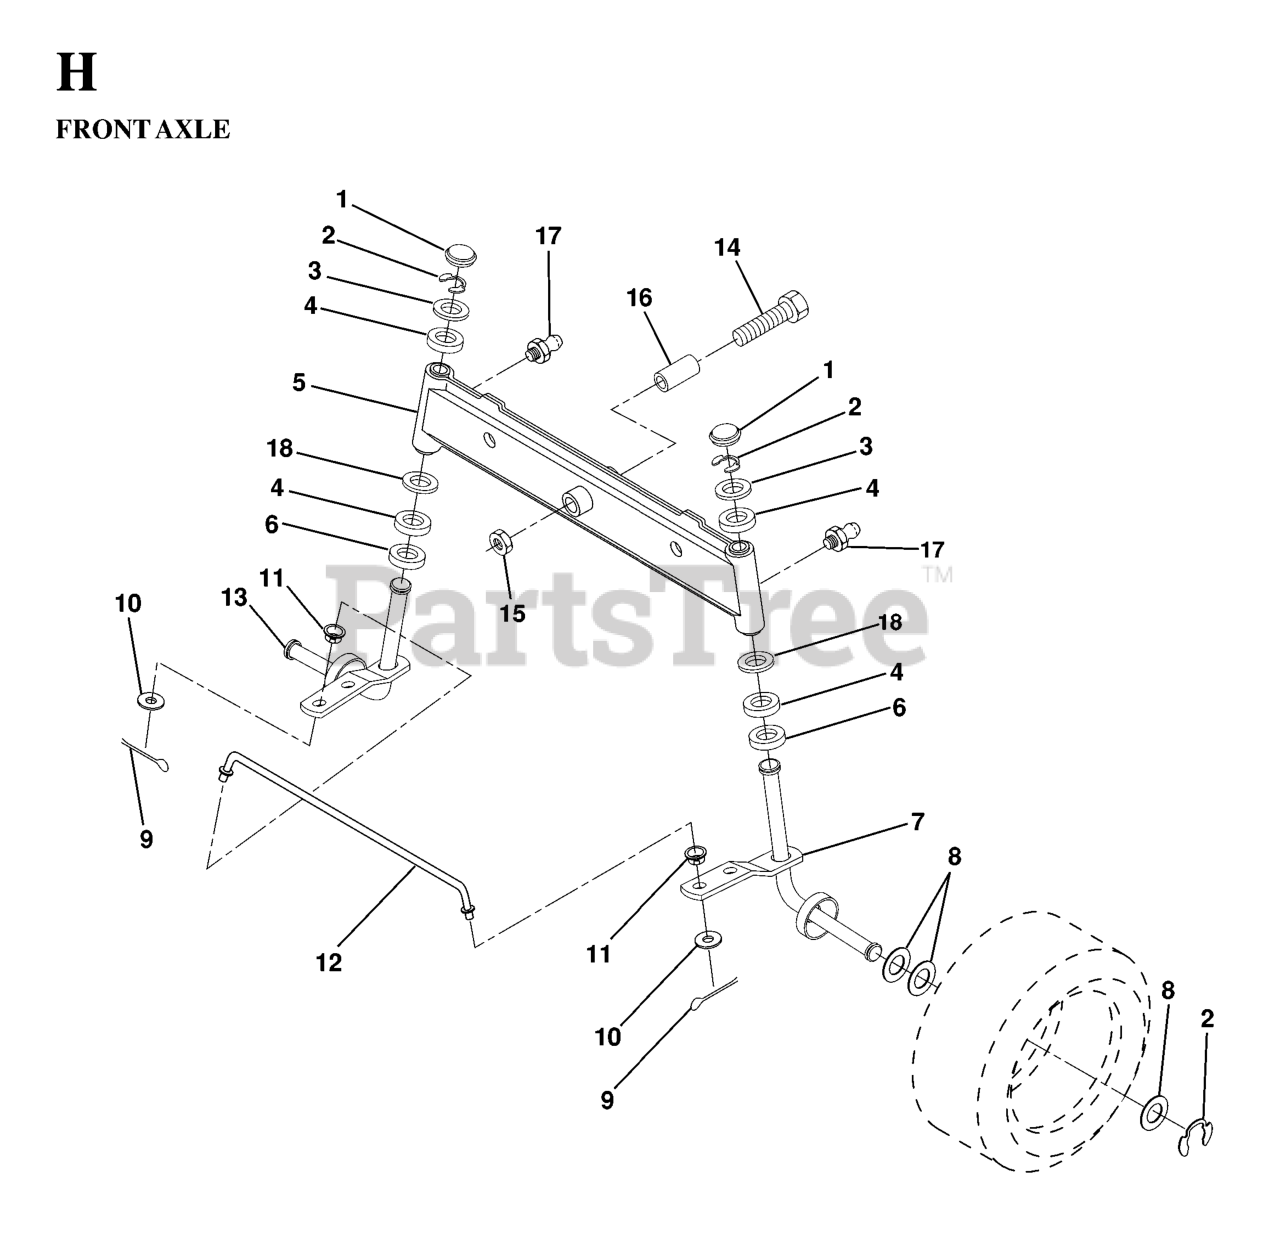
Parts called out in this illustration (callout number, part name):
1	CAP.SPINDLE.BLACK
4	BRNG T
6	THRUST WASHER
7	SPINDLE ASSY RH NLA
9	COTTER PIN
10	WASHER
11	BUSHING.DRAGLINK (2 2)
12	TIE ROD
13	SPINDLE ASSY LH
14	Bolt, Hex Head 5/8-11 x 3-1/2
15	NUT-LOC,FLANGE LT
16	BEARING
17	ZERK M
